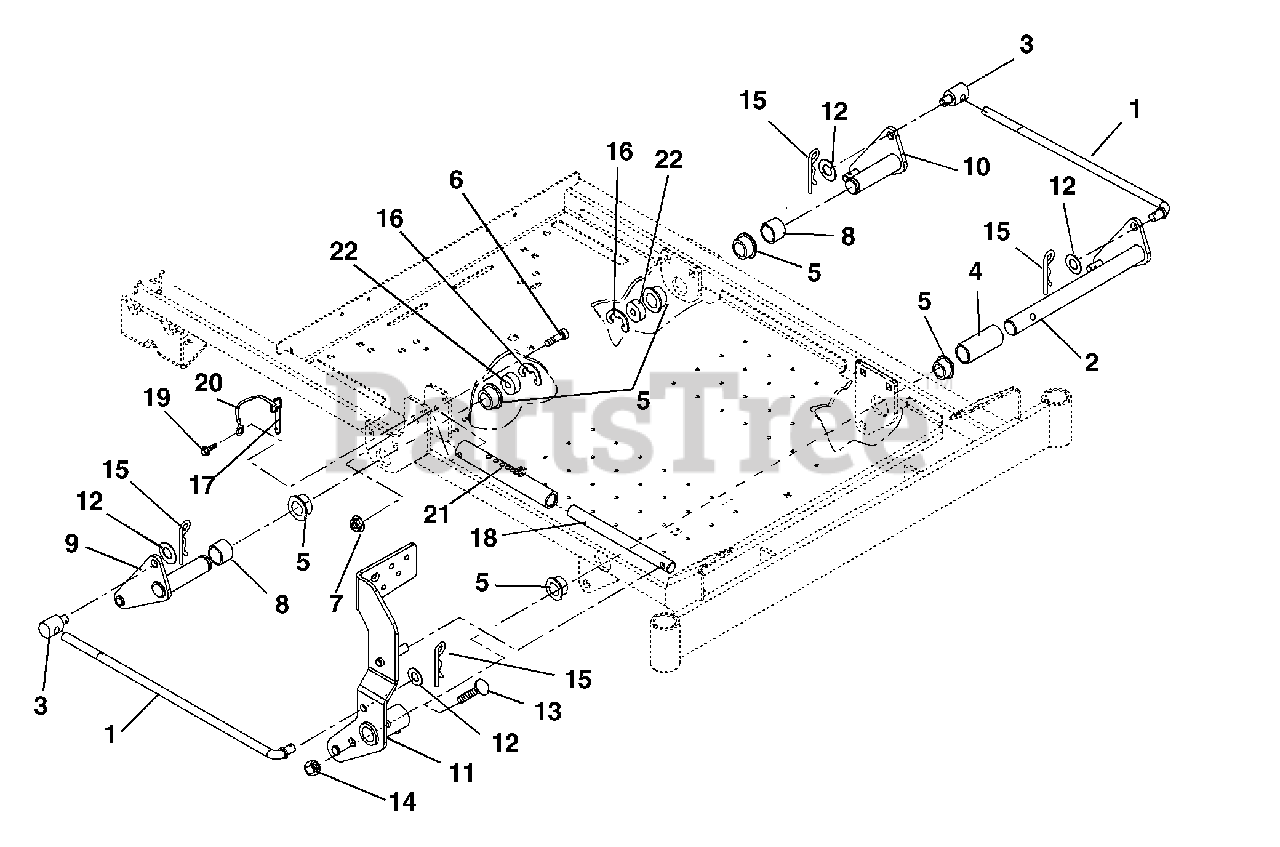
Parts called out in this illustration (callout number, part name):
1	LINKAGE, LIFT
2	WELDMENT,FRONT LIFT
3	TRUNNION-.50
4	BSHG, SPCR 1.01X1.25X2.63 PM
5	BSHG-FLG 1.000X1.12X.62X1.50BR
6	BLT, SKH SHLD .31X18X2.00
7	@NUT-LK-NYL-FLG .31-18 YWZC
8	BSHG-SPCR 1.032X1.250X.88 PM
9	WELDMENT, LIFT, REAR - RH
10	WELDMENT, LIFT, REAR - LH
11	WMT, FOOT PEDAL
12	WSHR-FL-STL.511X1.441X.125 YWZ
13	@BLT-HEX .38-16X2.00 GR5 YWZC
14	@NUT-LK-NYL-FLG .38-16 YWZC
15	PIN, HAIR, EXT - #16 YWZC
16	RG-RTNG .822X1.500X.050 TYP E
17	PIN, SPRING BALL .375OD X 1.50
18	ROD, LIFT
19	@SCR-TAP .25-20X.37 HWH YWZ TR
20	LANYARD
21	TUBE, LIFT STOP
22	BSHG, SPCR 1.032X1.25X.25 PM
